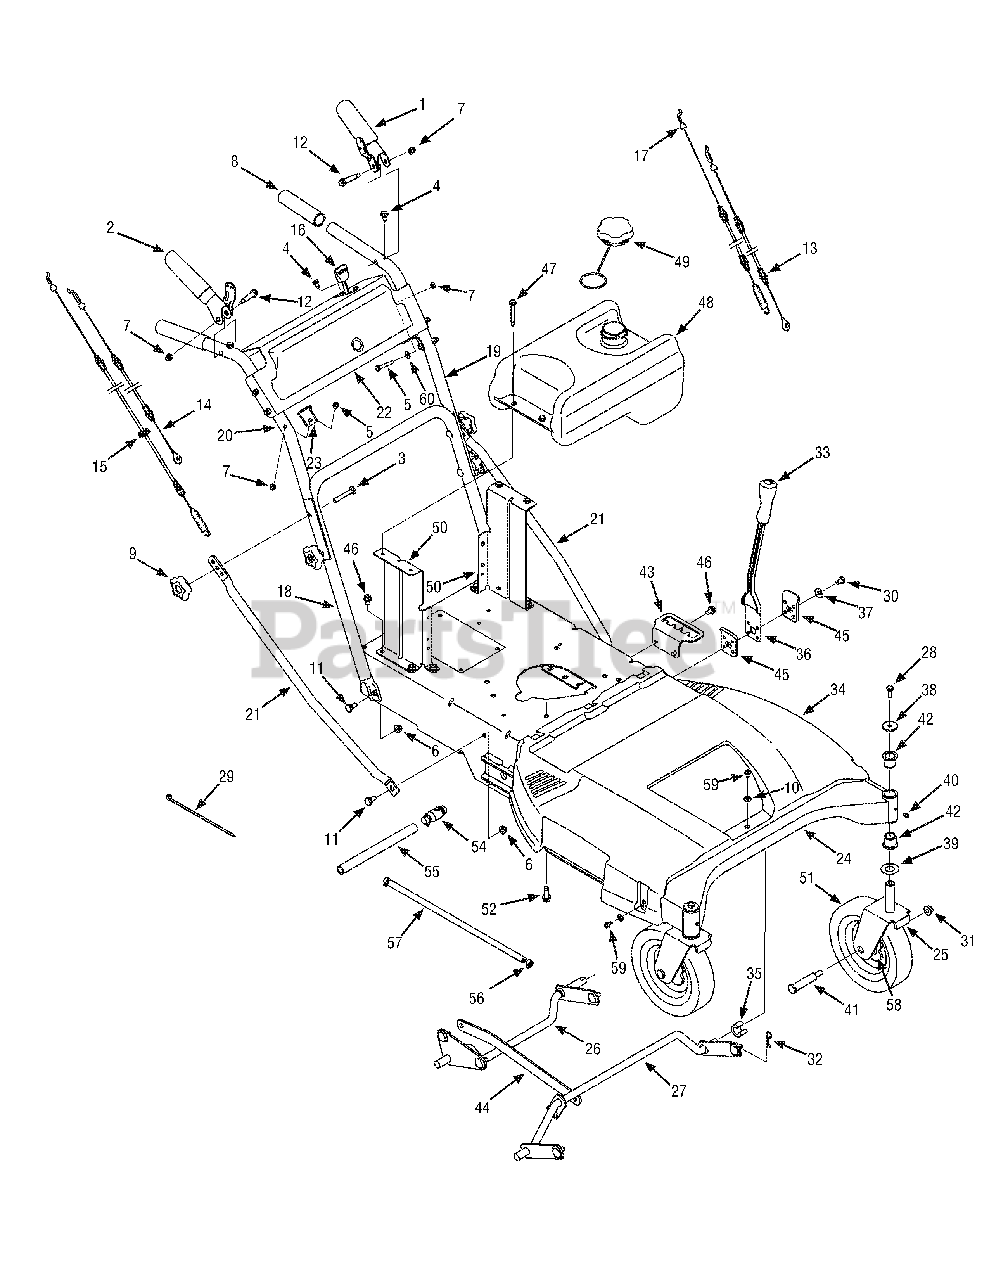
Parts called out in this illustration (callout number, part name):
1	Lever Assembly: LH
2	Lever Assembly: RH
3	Screw, Carriage: 5/16-18 x 2.25"
4	Screw, TT: 1/4-20 x 0.500"
5	Screw, HH Cap: 1/4-20 x 1.50"
6	Nut, Flange Lock: 5/16-18
7	Nut, Lock Cap: 1/4-20
8	Grip: 1.0" ID x 5.0" Lg
9	Star Knob 5/16-18
10	Washer, Flat: .25 x .63 x .0515
11	Screw, Shoulder: .435" x .178-5/16
12	Screw, Shoulder: .375" x 1.355" x 1/4-20
13	Cable, Clutch Wheel
14	Cable, Brake, Transmission: RH
15	Cable, Clutch Deck
16	Cable, Throttle/Choke: 38" x 1.1" Ext
17	Cable, Brake, Transmission: LH
18	Lower Handle
19	Upper Handle: LH
20	Upper Handle: RH
21	Brace Tube
22	Handle Panel
23	Cable Mount Bracket: RH
23	Cable Mount Bracket: LH
24	Frame Assembly
25	Caster Wheel Bracket Assembly
26	Deck Lift Assembly: RR
27	Deck Lift Assembly: Front
28	Screw, HH Cap: 5/16-24 x .750"
29	Cable Tie, 3/16 x .05 x 7.4
30	Screw, HH Cap: 5/16-18 x .50"
31	Nut, Flange Lock: 3/8-16
32	Click Pin: .092" x 1.64"
33	Handle Grip 1/2"
34	Belt Cover 33" Wide Cut Mower
35	Snap Spacer: .63" ID x .75" LG
36	Deck Height Lever
37	Washer, Bell: .340" x .872" x .060"
38	Washer, Flat: .330" x 1.25" x .120"
39	Washer, Flat: .760" ID x 1.50" OD
40	Lube Fitting: 3/16: LNC #70
41	Bolt, Shoulder: .625" x 2.515" x 3/8-16
42	Flange Bearing: .760" x .941" x 1.0"
43	Height Adjustment Bracket
44	Link Pivot Bracket
45	Lever Pivot Bracket
46	Screw, TT: 5/16-18 x .625"
47	Screw, Shoulder: .3175" x .188" x 1/4-20
48	Fuel Tank, 2 Gal.
49	Fuel Cap
50	Fuel Tank Mounting Bracket
51	Wheel, 8" x 1.75"
52	Screw, TT: 3/8-16 x 1.25"
54	Oil Drain
55	Oil Drain Hose
56	Hose Clamp
57	Fuel Hose
58	Flange Bearing, .635"
59	Screw, 1/4-14 x .625
60	Washer, Bell: .265" x .75" x .062"
